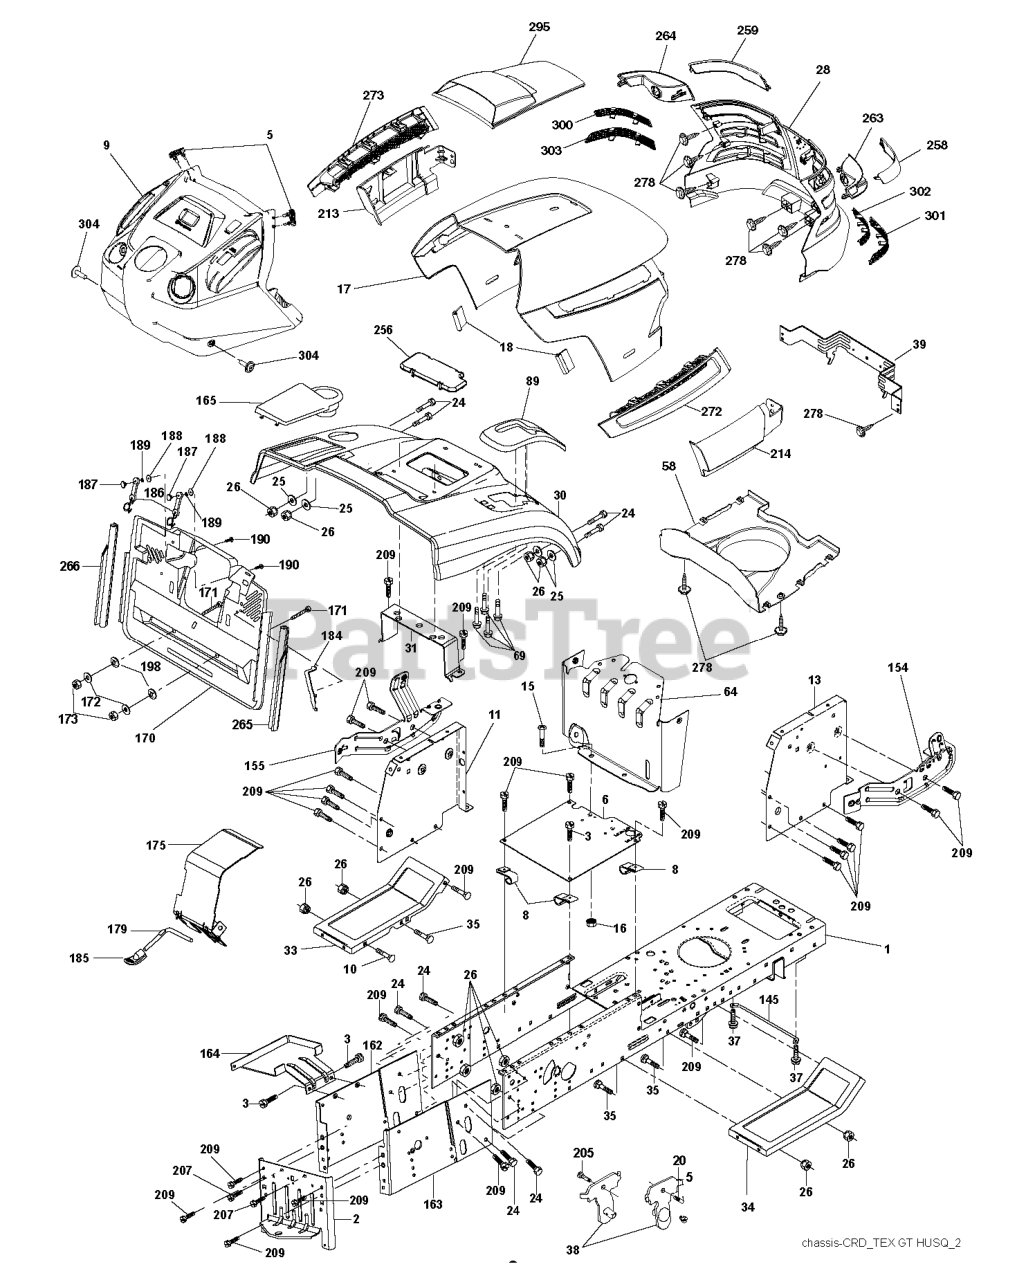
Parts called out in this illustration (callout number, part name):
2	DRAWBAR
3	SCREW 3/8-16X3/4
5	BUMPER DASH
6	PLATE
8	CLIP,INSULATOR
10	BOLT D
11	PANEL DASH LH
13	PANEL DASH RH
15	Screw, Machine, Truss Head 5/16-18 UNC x 3/4
16	NUT
17	HOOD
18	BUMPER.HOOD.TEX.HUSQVARNA
25	WASHER
26	NUT
28	GRILL.ASM.HUSQ.TG/CRD.W/TRIM
30	CONSOLE.CRD.AUTO.GRY
31	BRACKET SUPPORT FENDER
33	FOOTREST PNT LH
34	FOOTREST PNT RH
37	Screw 5/16-18 x 1/2 Hex, Self Tapping 5/16-18 x 1/2
38	BRACKET ASM PIVOT MOWER REAR
39	HOOD PIVOT BRACKET
58	AIR.DUCT.HOOD.TEX.GT.HUSQ
69	SCREW.HI-LO.CONSOLE
89	CONSOLE.CRD.AUTO.GREY.2005
145	ROD.PIVOT.HOOD
162	BRACKET
163	BRACKET EXTEN CHASSIS RH CRD
165	RP.COVER.BATTERY.CRD.GREY
172	WASHER
175	DOOR TRAP
179	ROD PIVOT FBI
184	BRACKET.ACTUATOR.BAGGER.SRD
186	LATCH ASSY
187	WELDNUT
189	LOCKWASHER #10
190	SCREW
207	SCREW, 5/16-18 X 1/2
209	SCREW, 3/8-16X3/4
213	SKIRT.HOOD.SIDE.HUSQ.LH.GREY
214	SKIRT.HOOD.SIDE.HUSQ.RH.GREY
256	COVER FENDER CRD
258	LENS.RH.TEX.GT.HUSQ.CL
259	LENS.LH.TEX.GT.HUSQ.CL
263	BEZEL.RH.TEX.GT.HUSQ
264	BEZEL.LH.TEX.GT.HUSQ
265	SEALING
266	SEALING
272	VENT.SIDE.HOOD.HUSQ.RH.GREY
273	VENT.SIDE.HOOD.HUSQ.LH.GRAY
278	SCREW.#10 X 0.750.BOS
295	VENT.ASM.TORPHD.HUSQGT.LOGO.CL
300	INSERT.HEX.GRILL.HUSQ.
301	INSERT.HEX.GRILL.HUSQ.GREY
302	INSERT.HEX.GRILL.HUSQ.
303	INSERT.HEX.GRILL.HUSQ.
304	SCREW 14-20 X 5/8
